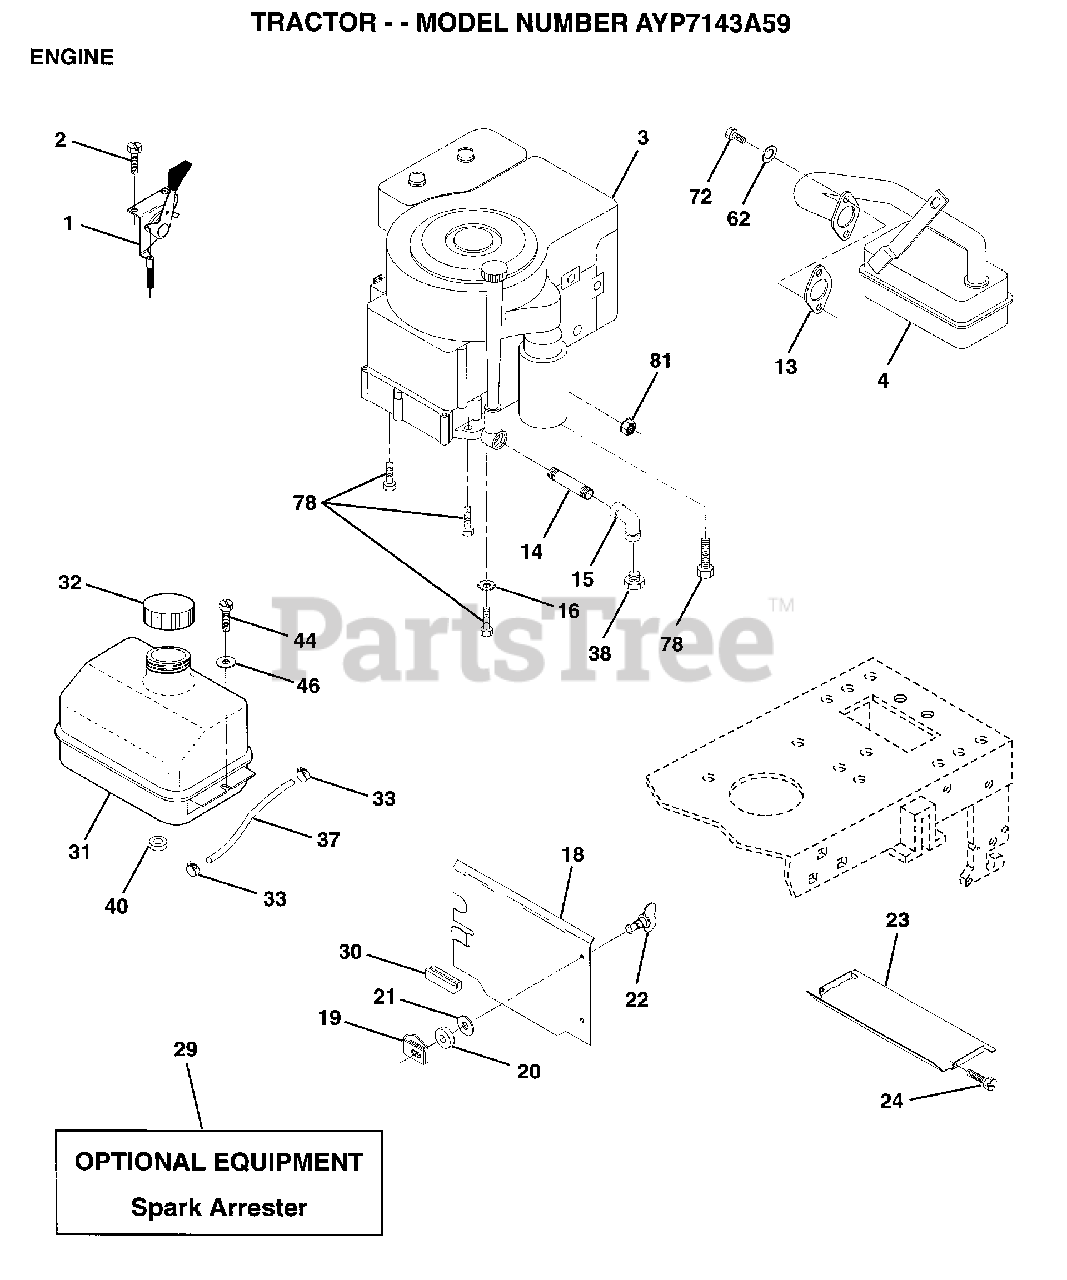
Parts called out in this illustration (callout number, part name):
2	SCREW LT
4	MUFFLER
14	PIPE NIPPLE
15	ELBOW
16	LOCKWASHER
18	SHIELD HEAT
19	RECEPTACLE LT
20	RETAINER LT
21	WASHER
22	STUD.1/4.TURN
23	HEAT SHIELD
24	SCREW
31	TANK.FUEL.LT.
32	CAP ASM FUEL
33	HOSE CLAMP
37	LINE FUEL
44	SCREW HEX CRT
46	WASHER
62	LOCKWASHER
72	SCREW
78	SCREW
81	NUT
